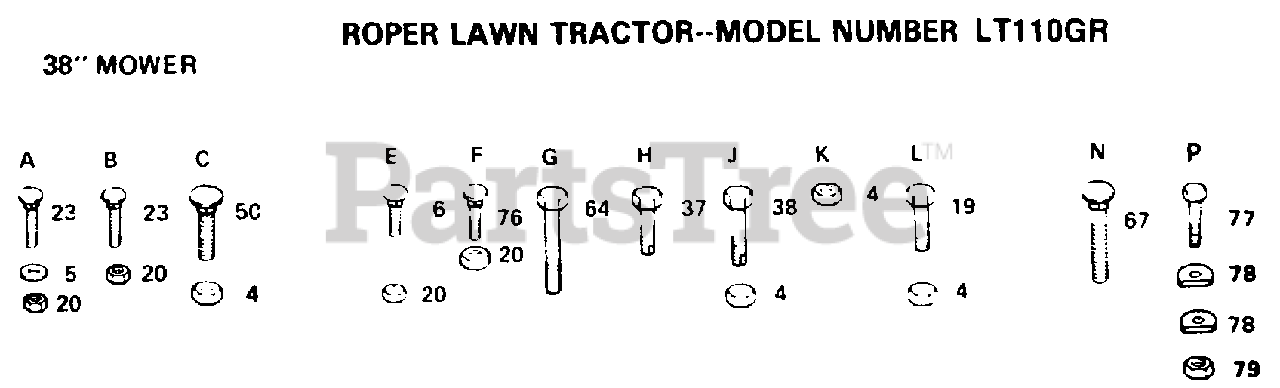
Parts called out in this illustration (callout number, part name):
5	WASHER M
6	BOLT
23	BOLT
37	SCREW
38	SCREW
50	BOLT
57	"ROD, BRAKE LH LT"
77	BOLT LT
78	WASHER T
